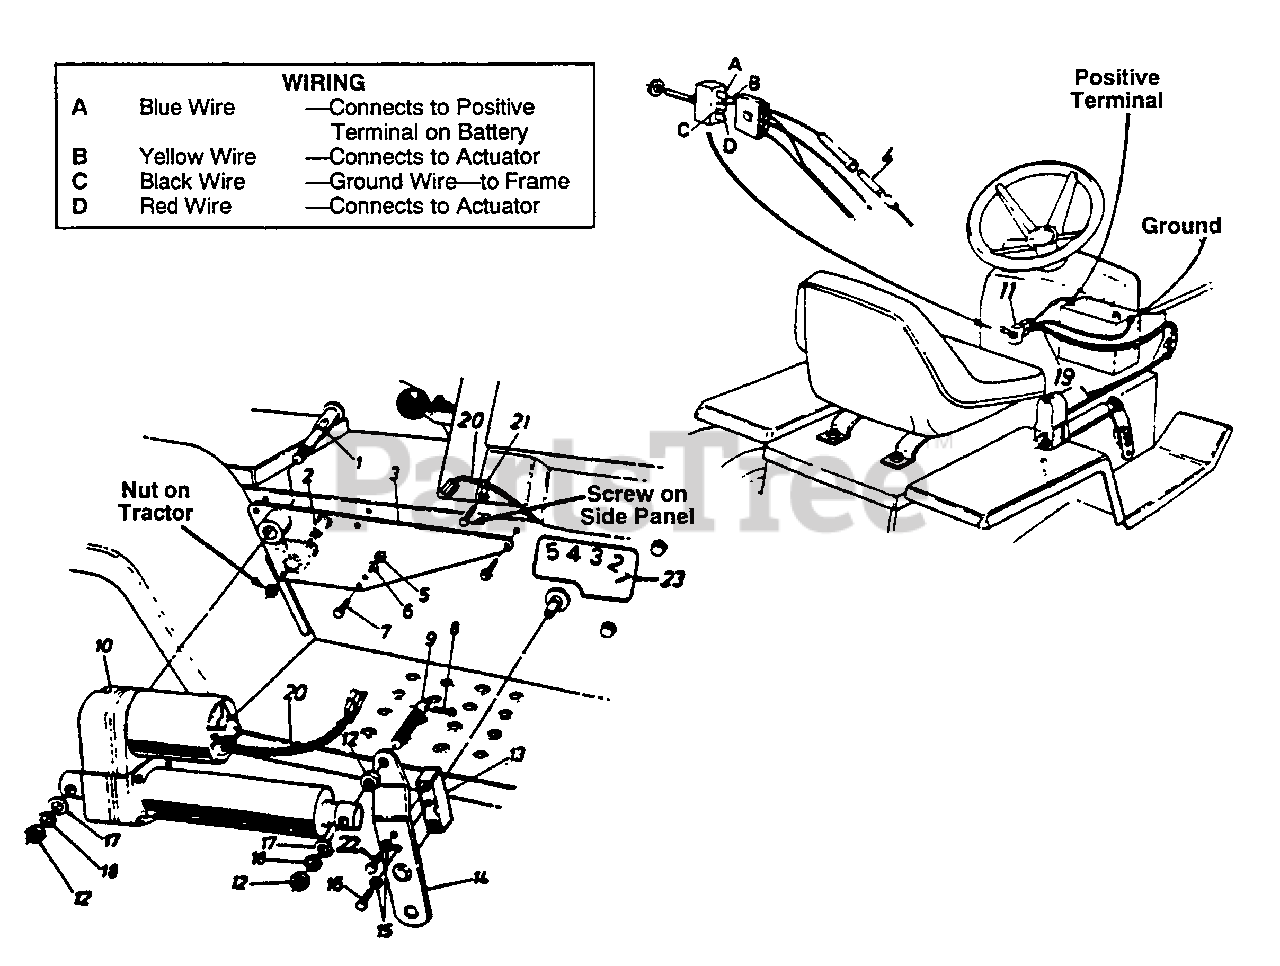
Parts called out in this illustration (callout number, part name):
1	Pivot Pin
2	Shld. Bolt .626" Dia. x .96"
5	Hex Nut 1/4-28 Thd.
6	L-Wash. 1/4" I.D.
7	Hex Bolt 1/4-28 x .75" Lg. (Grade 5)
8	Cotter pin
9	Indicator & Mtg. Pin
10	Electric Actuator
11	Toggle Switch
12	Hex Jam Nut 1/2-13 Thd.
13	Lift Shaft Drive
16	Hex Bolt 5/16-24 x 1.0" Lg. (Grade 5)
17	Fl-Wash. .53" I.D. x .93" O.D.
18	L-Wash. 1/2" I.D.
19	Wire Harness
20	Plastic Tubing - 7"
21	Clamp
22	Hex Bolt 5/16-18 x 1" Lg. (Grade 5)
23	Label
A	Connects to Positive Terminal on Battery
B	Connects to Actuator
C	Ground Wire - to Frame
D	Connects to Actuator
